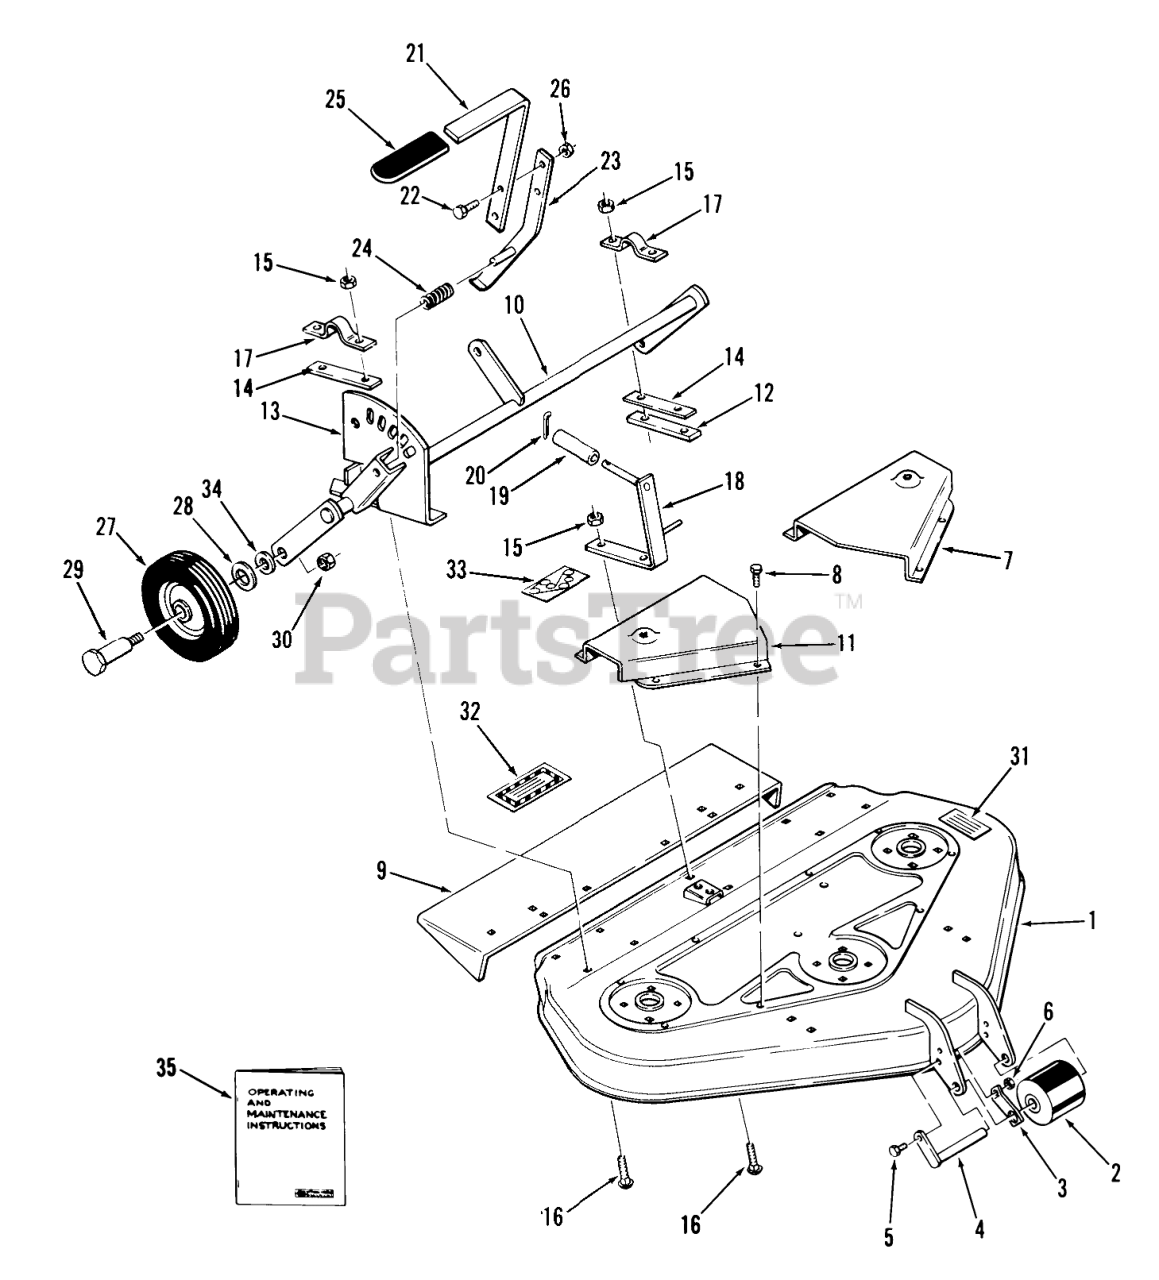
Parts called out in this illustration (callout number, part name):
1	ASSY-MOWER DECK 3 R
1	ASSY-MOWER DECK RH
2	Roller
3	SPRING ROLLER STOP
4	Roller Shaft
5	H H C S
6	Nut
7	Cover-Belt
8	Bolt
9	Chute Extension
10	Gage Wheel Support
11	Belt Cover RH
12	Strap
13	Quadrant
14	Strap 1/16
15	Nut
16	Bolt
17	CLAMP
18	Bracket Guide Assembly
19	SPACER
21	HANDLE-EXTENSION R
22	Bolt
23	Lever
24	SPRING-COMPRESSION
26	Nut
27	Wheel 6 x 1.75
28	WASHER
29	BOLT-SHOULDER
30	Nut
31	Caution Decal
32	Decal-Caution
33	DECAL-HEIGHT BELT
34	WASHER
35	Operating and Maintenance Instructions
